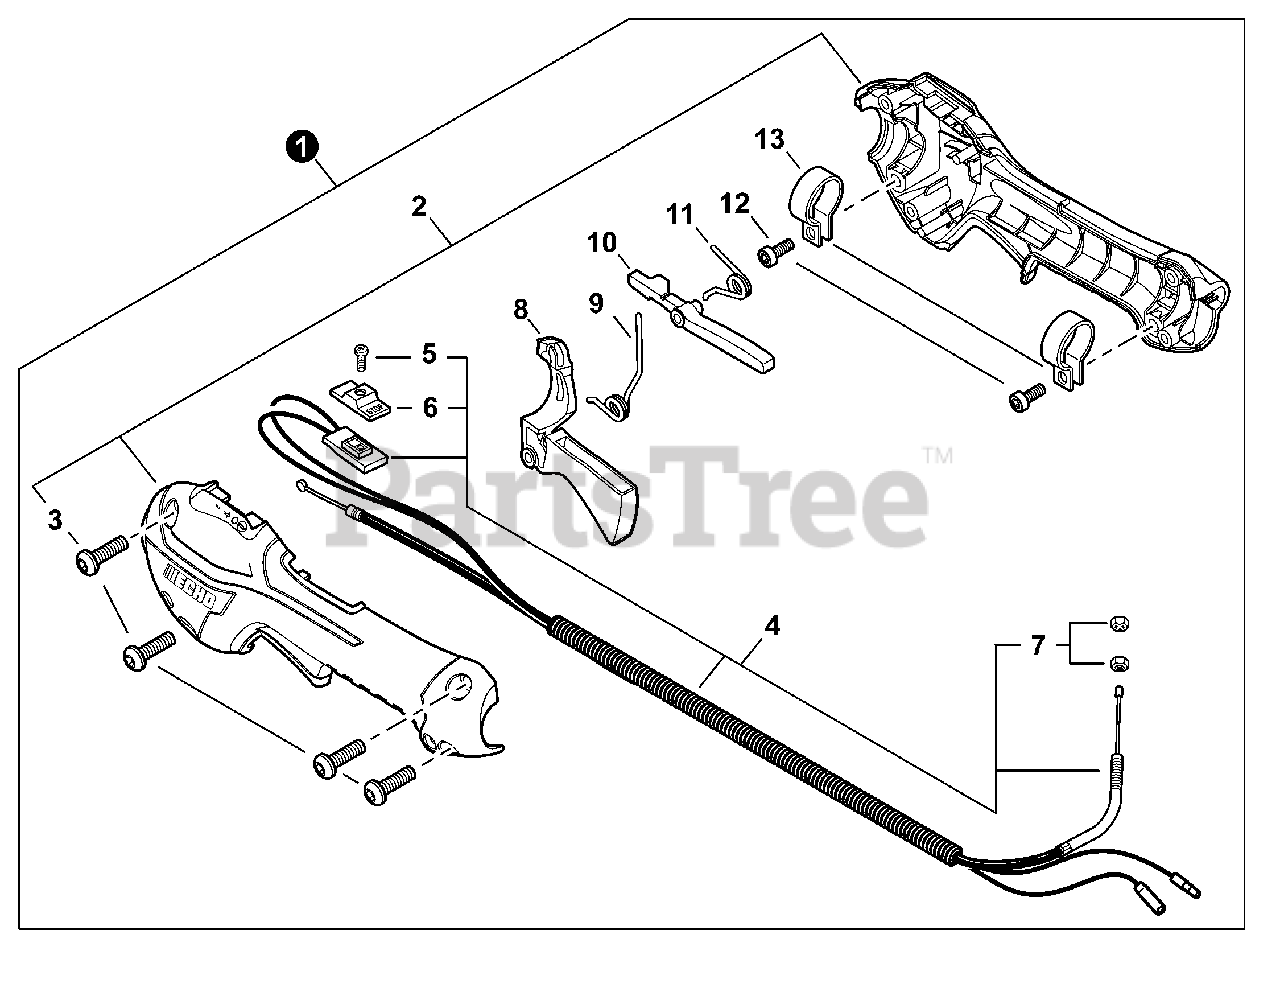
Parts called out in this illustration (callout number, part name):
1	CONTROL HANDLE ASSY
2	CONTROL HANDLE KIT
3	BOLT, TORX 5×16
4	CONTROL HANDLE KIT
5	SCREW 3×10
6	KNOB, SWITCH - ORANGE
8	TRIGGER, THROTTLE
9	SPRING, TORSION
10	LEVER, THROTTLE LOCKOUT
11	SPRING, TORSION
12	BOLT, TORX 5×16
